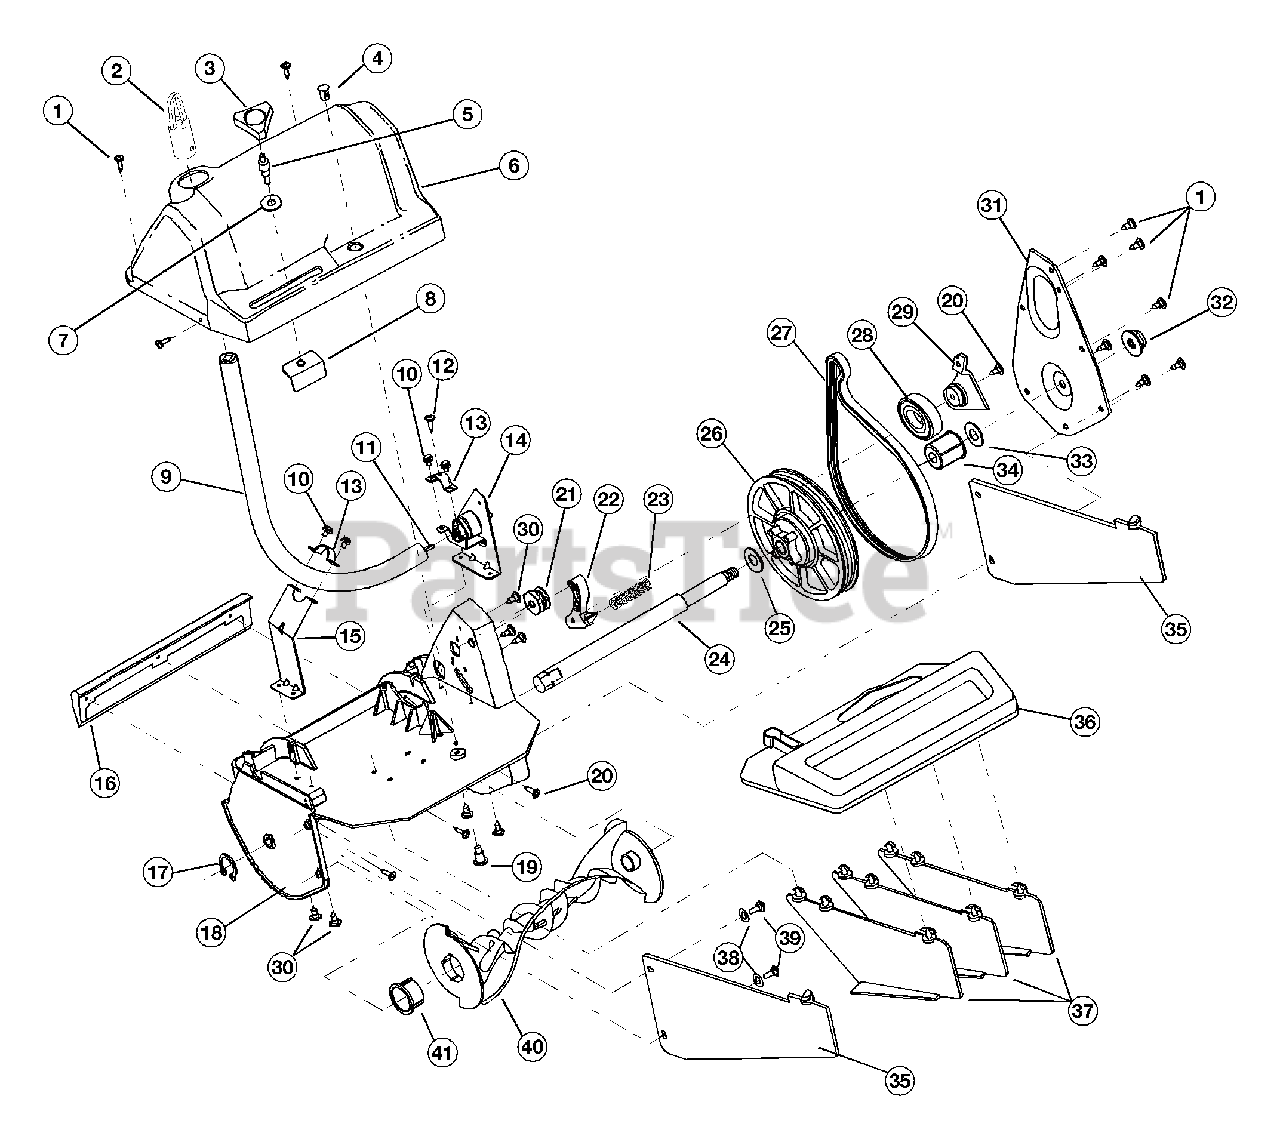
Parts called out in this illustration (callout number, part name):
2	Hanger Accessory
3	Vane Actuator Knob
4	Grommet
5	Vane Actuator Shaft
7	Vane Actuator Washer
8	Vane Actuator Bracket
9	Drive Housing Assembly
11	Flexible Drive Shaft
14	Power Shaft Assembly
15	Drive Housing Bracket
16	Scraper
17	Retaining Ring
18	Snowthrower Housing
21	Drive Pulley
22	Idler Arm
23	Idler Spring
24	Rotor Shaft
26	Driven Pulley
27	Drive Belt
28	Ball Bearing
29	Idler Pulley Retainer
31	Belt Case Cover
32	Flange Lock Nut
33	Thrust Washer
34	Left Rotor Bushing
35	Outer Vane
36	Vane Mount
37	Center Vane
41	Right Rotor Bushing
